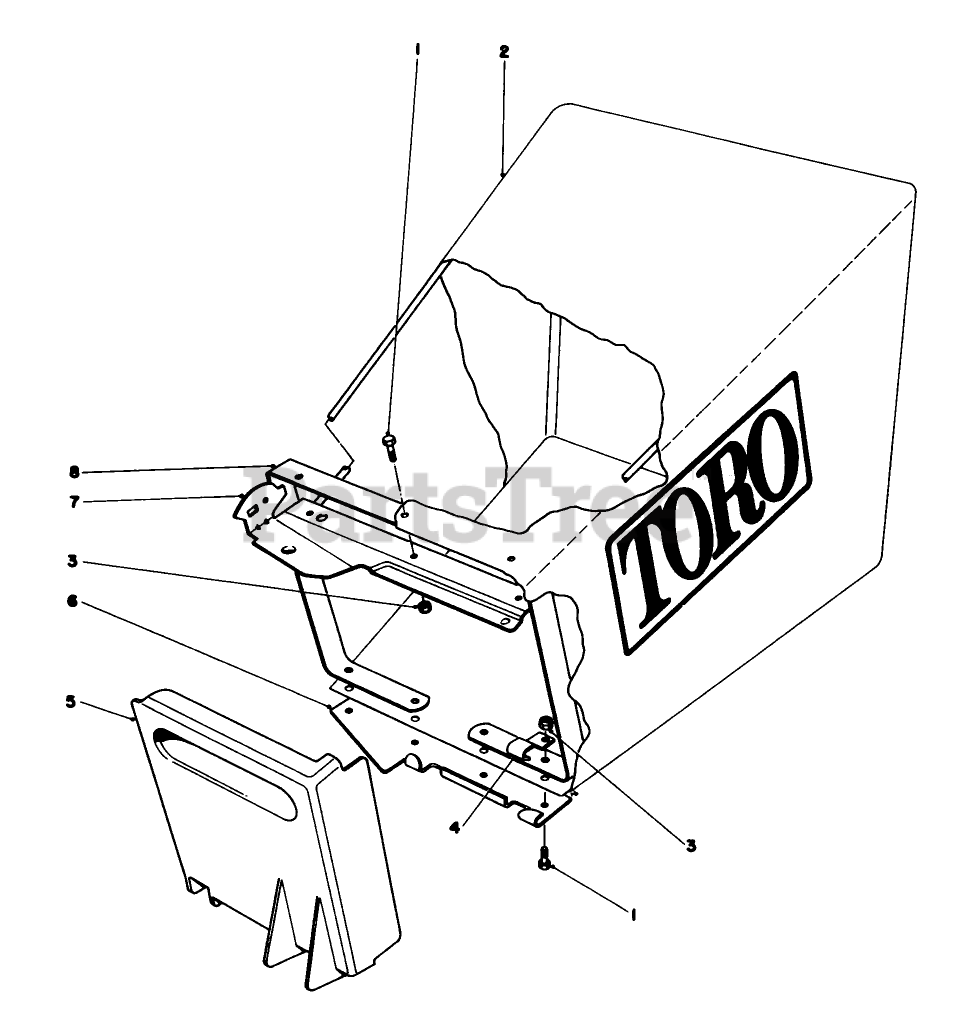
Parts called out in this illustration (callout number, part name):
1	SCREW-HWH
3	216 Washer
5	BAG DOOR
7	BAG FRAME ASM
8	LOWER BAG FRAME
